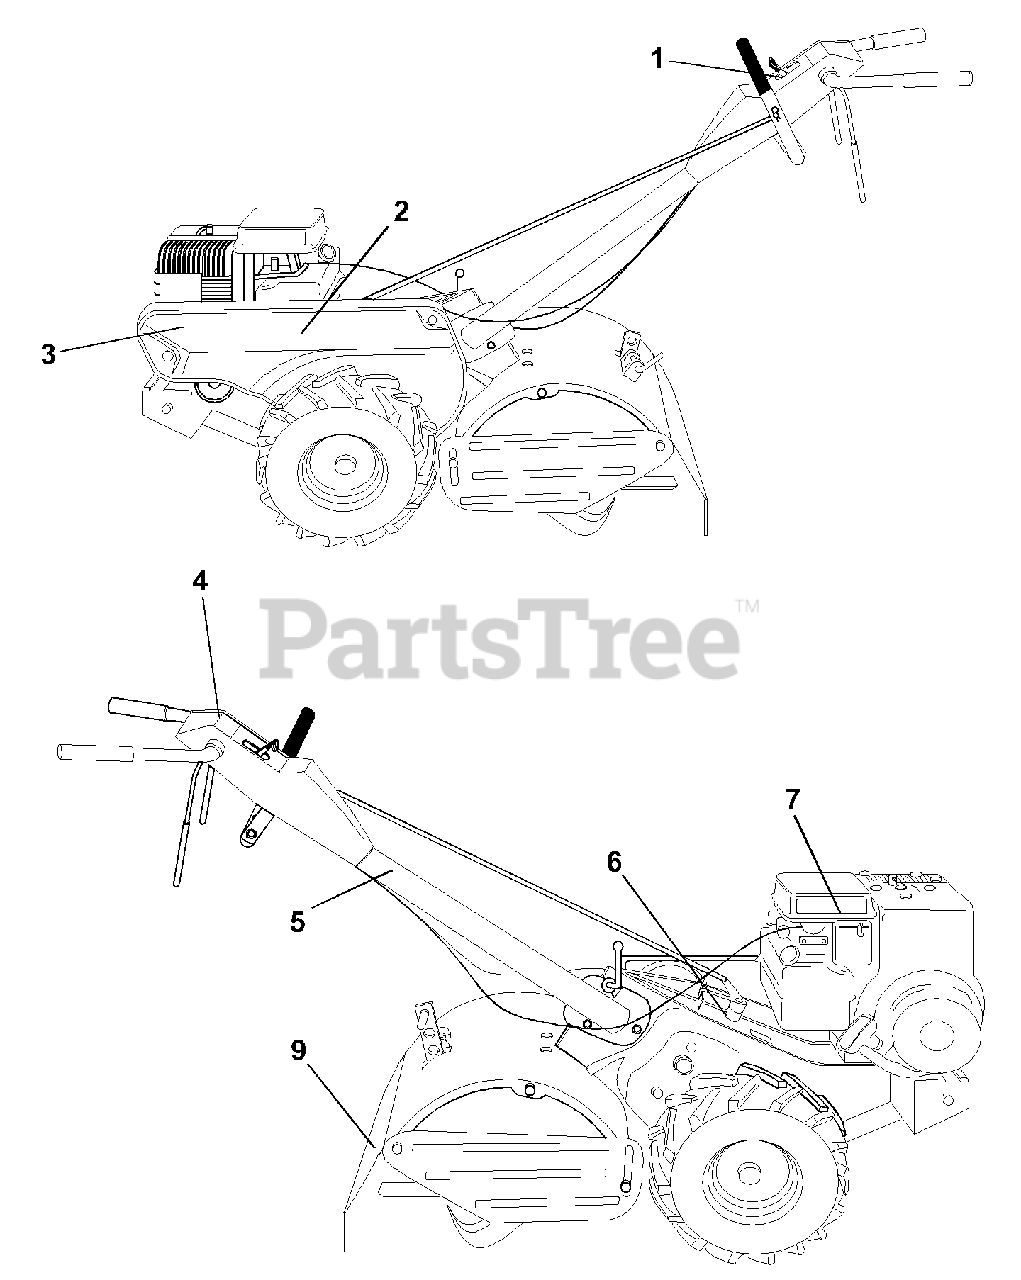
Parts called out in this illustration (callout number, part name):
1	Decal, Logo
2	Decal, Nameplate
3	Decal, Logo
4	Decal, Instruction, Tilling
5	Decal, Hand Placement
6	Decal, Shift Indicator
7	Decal, Caution
9	Decal, Warning, Rotating Tines
